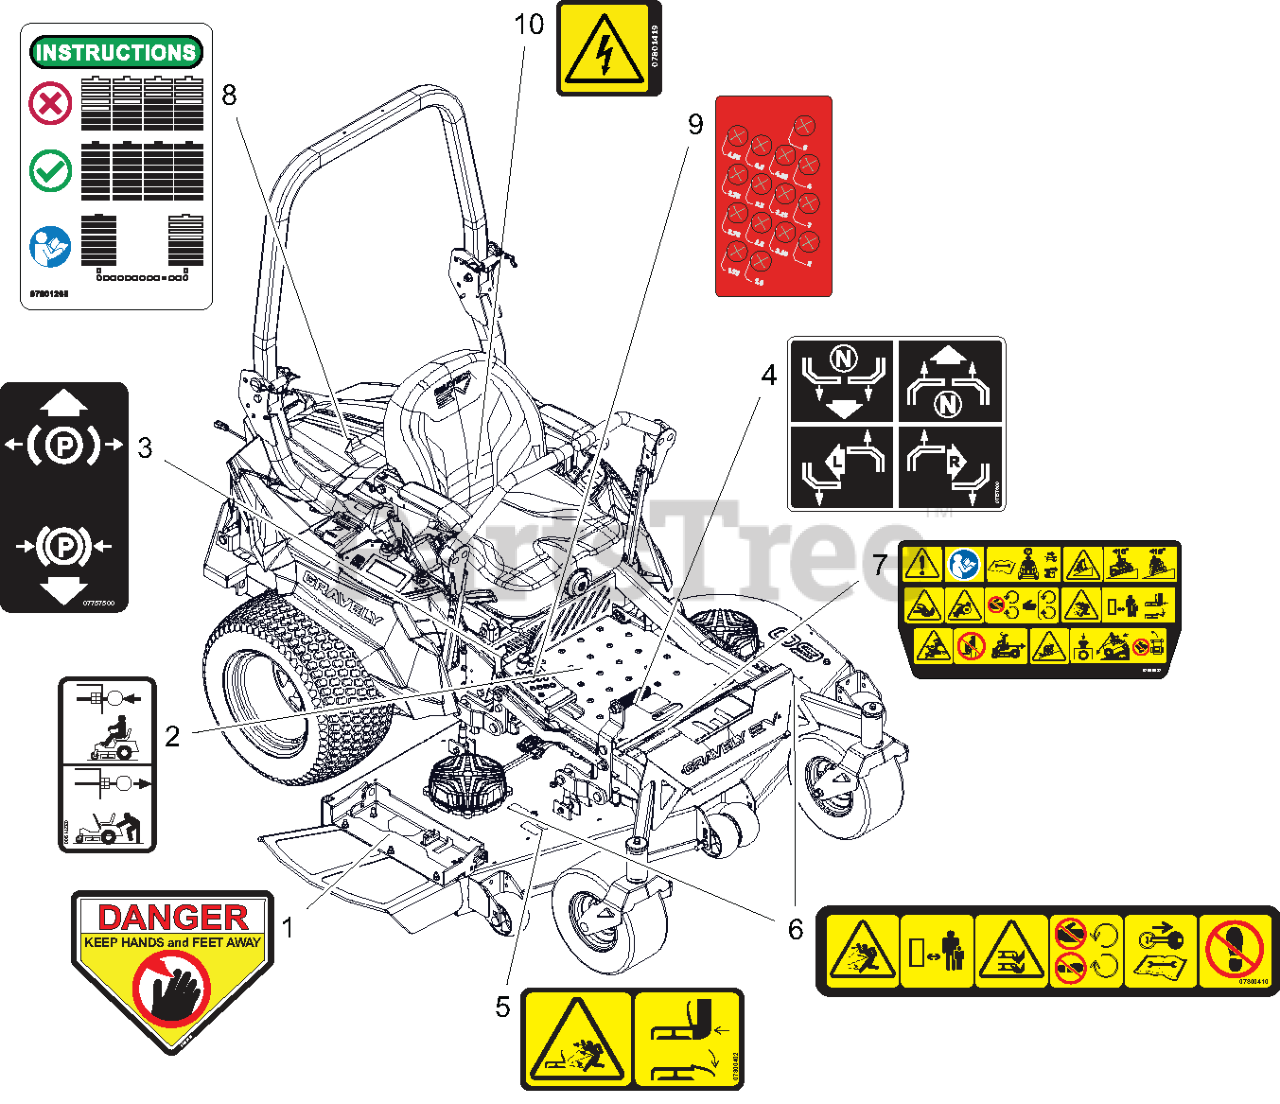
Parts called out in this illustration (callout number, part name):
1	DECAL, DANGER
2	DECAL, TRANSMISSION DISCONNECT
3	DECAL, PARKING BRAKE LEVER
4	DECAL, INSTRUCTIONAL-STEERING
5	DECAL, SAFETY - DECK GUARDING
6	DECAL, DECK SAFETY
7	DECAL, MAIN SAFETY
8	DECAL, BATTERY BALANCE
9	DECAL, HEIGHT OF CUT
10	DECAL, SAFETY - DANGER
